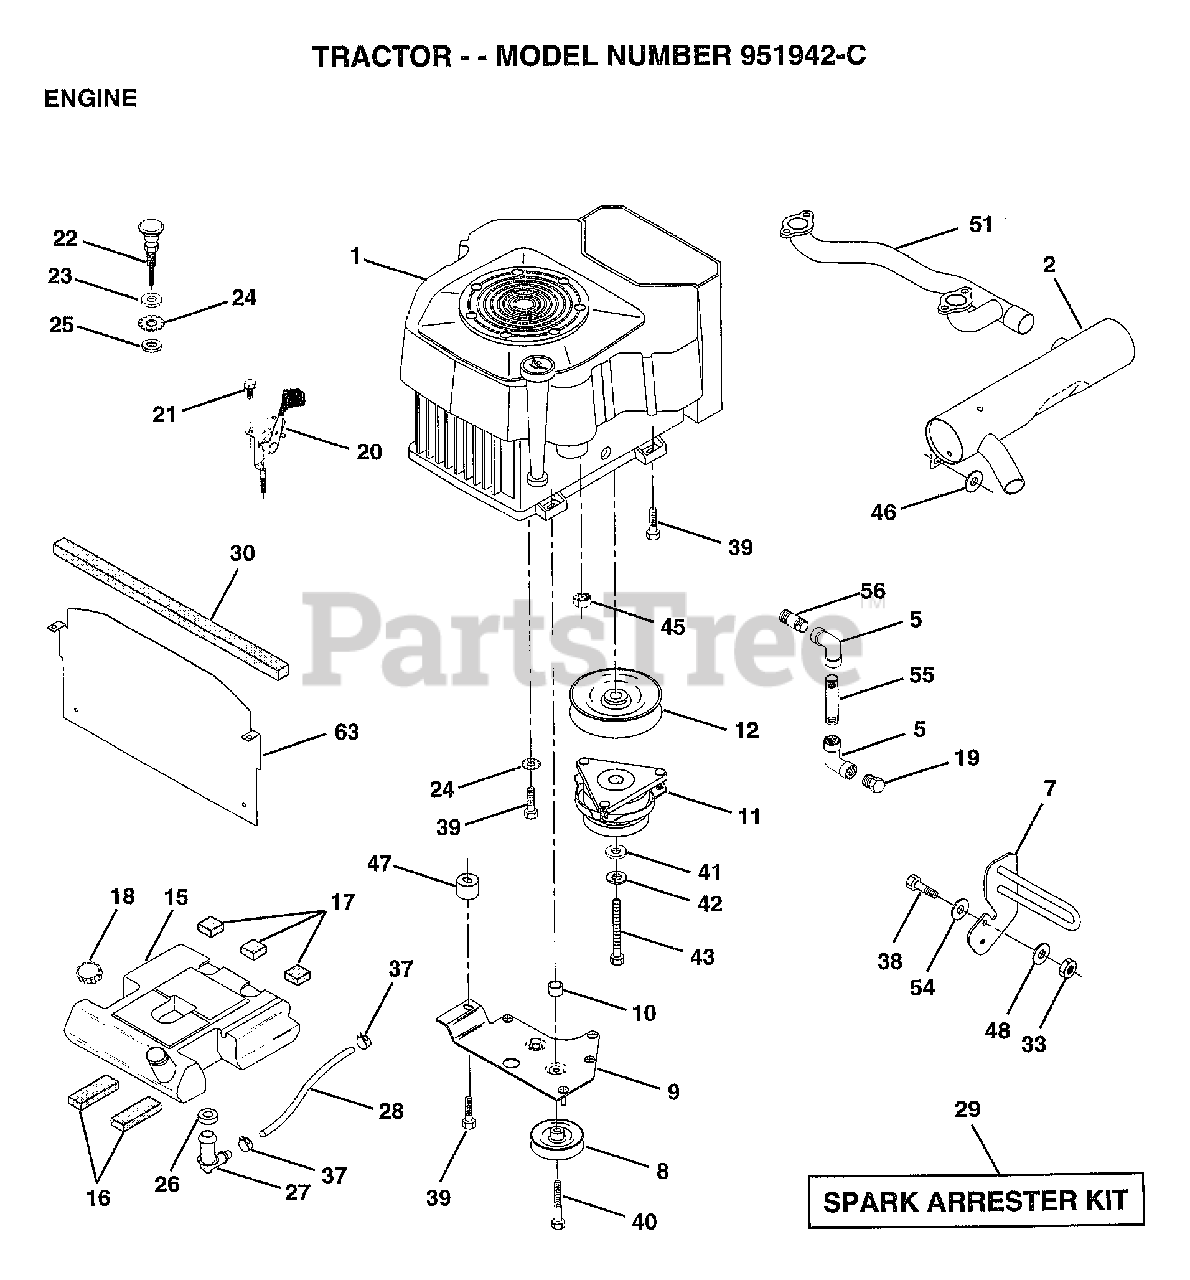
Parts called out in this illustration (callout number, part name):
5	ELBOW
10	BUSHING.
12	PULLEY.ENG.CLUTCH
16	PAD IDLER TI
17	PAD-SPACER LT
18	CAP ASM FUEL
19	PLUG T
21	SCREW LT
22	CHOKE CONTROL
23	WASHER
24	LOCKWASHER
26	BUSHING OUTLET T
27	STEM.TANK.FUEL
29	SPARK ARREST KIT
30	FOAM-STRIP LT
33	NUT
37	HOSE CLAMP
38	"BOLT,HEX"
39	SCREW.3/8-16X2.25
40	SCREW.TT.3/8-16X4
41	WASHER
42	LOCKWASHER
45	NUT
46	WASHER HYT
47	SPACER.ENGINE
48	WASHER T
54	WASHER
56	NIPPLE.PIPE
63	HEAT.SHIELD.VGT.
